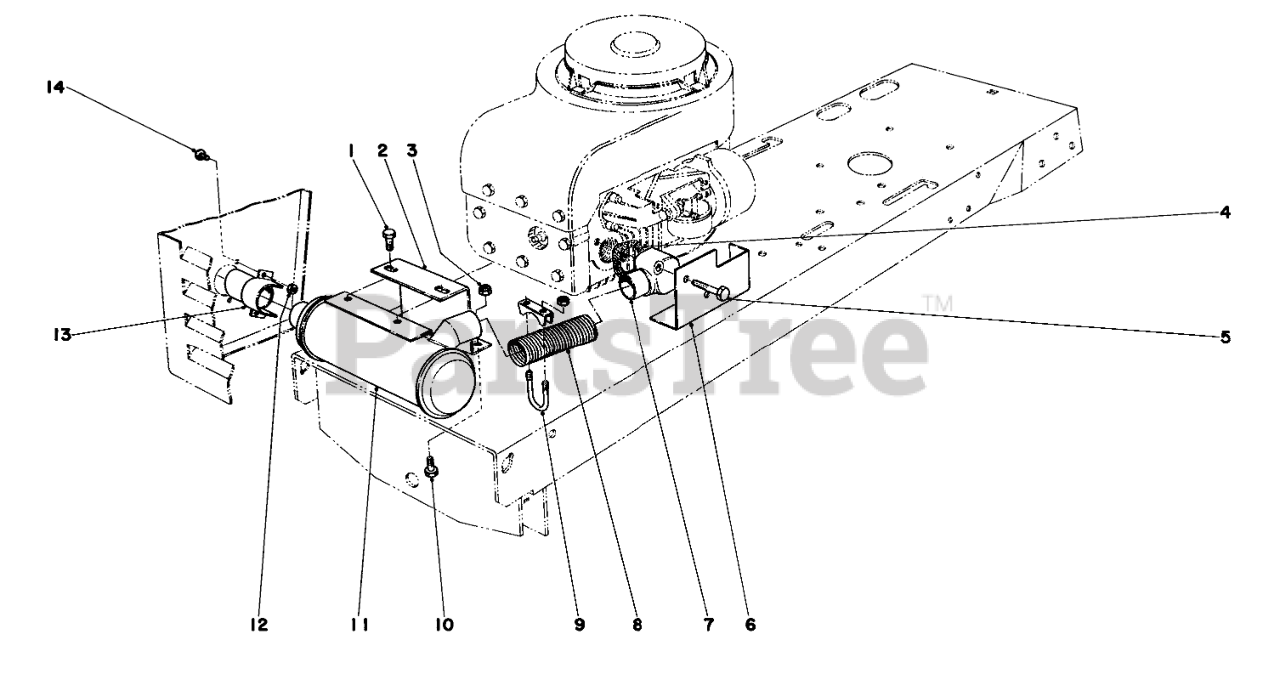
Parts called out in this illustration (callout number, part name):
1	SCREW-HH
2	Support-Muffler
3	NUT-LOCK, CONE
4	Gasket
5	Capscrew
6	Baffle Heat
7	Elbow Exhaust
8	Exhaust Tubing
9	Muffler Clamp
10	SCREW-HH
11	Muffler
12	NUT-LOCK, SIDE
13	Exhaust Tip
14	SCREW-PPH
